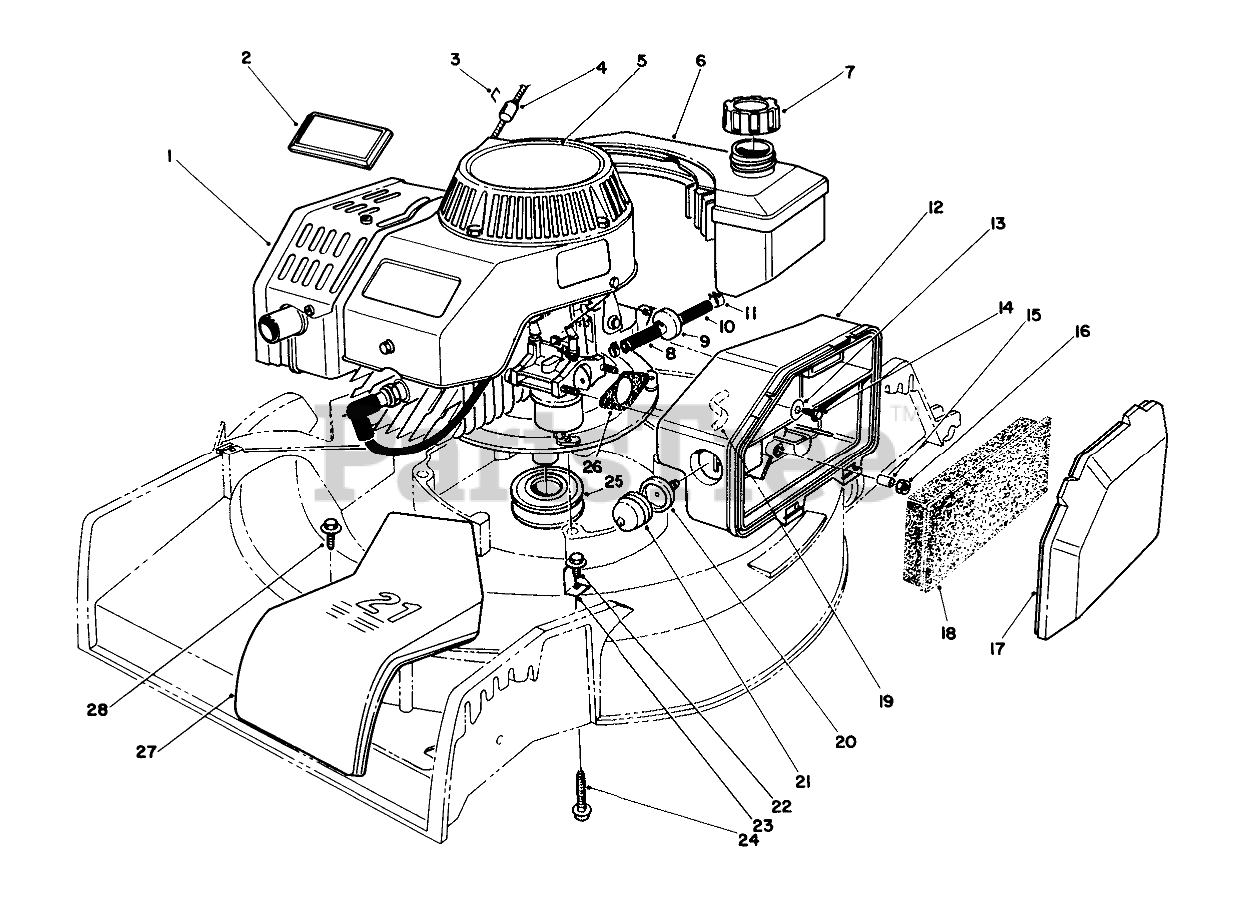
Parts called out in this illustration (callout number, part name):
1	Engine
2	TORO LOGO PLT
3	Staple
5	DECAL - 2 CYC RECOIL
6	FUEL TANK ASM
7	GAS CAP ASM
8	HOSE-FUEL
9	FILTER-FUEL
10	HOSE-FUEL
11	CLAMP-FUEL LINE
12	BODY-AIR CLEANER
13	WASHER-FLAT
14	SCREW-HH
15	SPACER
17	COVER-AIR CLEANER
18	ELEMENT-AIR CLEANER
19	HOSE-PRIMER
20	BODY-PRIMER
21	BULB-PRIMER
22	SCREW-HWHTF
23	BELT GUIDE
24	SCREW-HHF, WHIZ
25	PULLEY-DRIVER
26	GASKET-AIR CLEANER
27	BELT COVER 21" S D
28	SCREW
